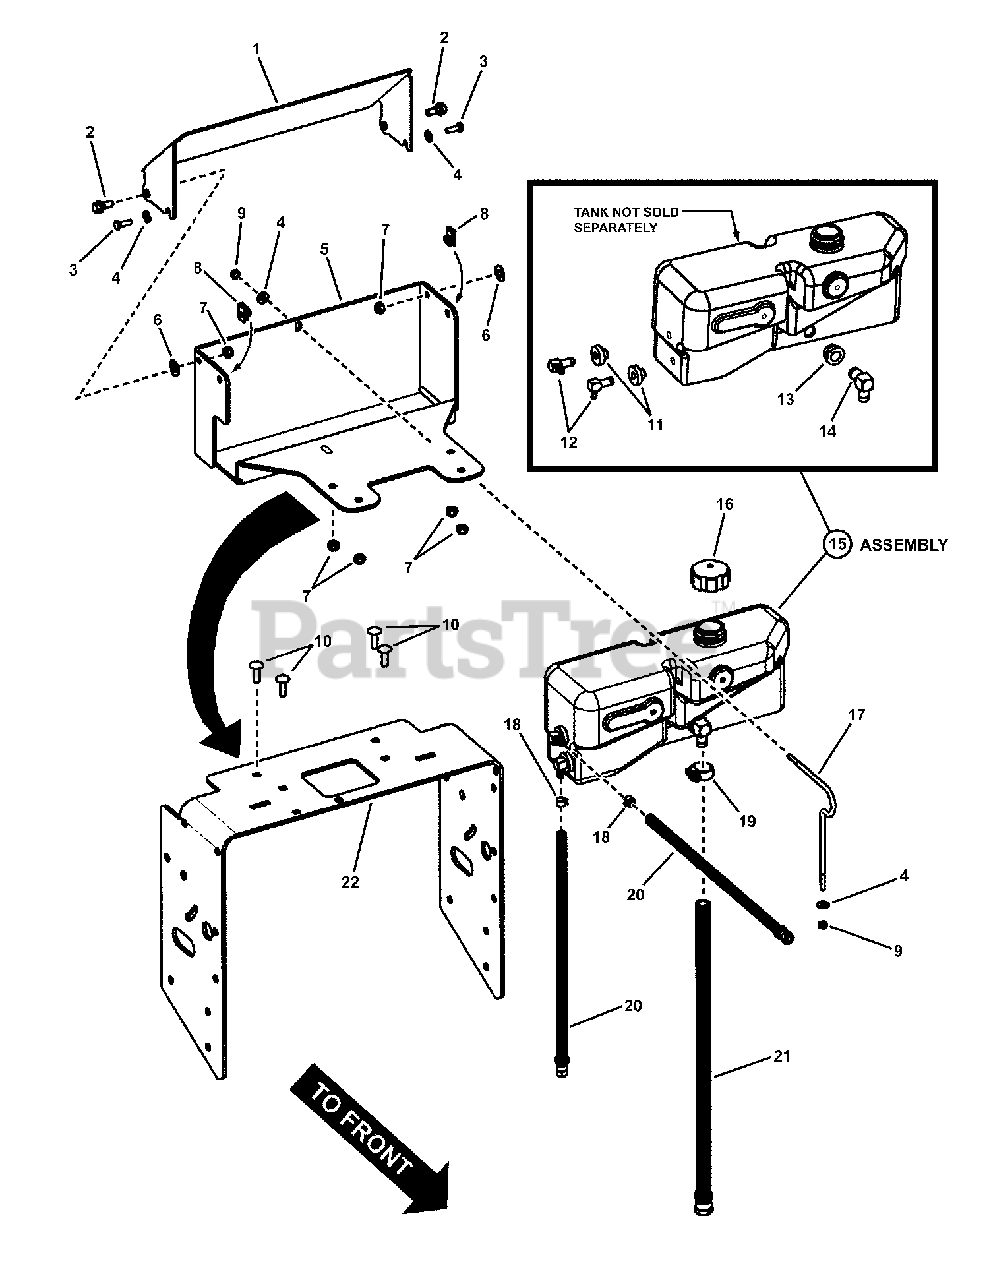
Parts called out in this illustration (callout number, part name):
1	COVER, Oil Tank Bracket
2	SHOULDER BOLT, 5/16-18
3	SCREW, 1/4-20 x 3/4" Hex Head Cap, GR 5
4	WASHER, .28 x .63 x .06 Flat
5	BRACKET, Reservoir, Hydro
6	WASHER, 3/8" Curved
7	NUT, 5/16-18 HEX NYLON LOCK
8	U-NUT 1/4-20
9	NUT, 1/4-20 Hex Top Lock, GR B
10	BOLT, 5/16-18 x 1" Short Neck Carriage, GR 5
11	GROMMET
12	*ELBOW
13	GROMMET
14	*ELBOW
15	OIL TANK (Includes Cap)
16	CAP, Oil Tank, Vented
17	RETAINING ROD, Reservoir (1/4-20 threads)
18	CLAMP, Fuel Hose
19	CLAMP, 13/16" Hose
20	HOSE, Return, 15-1/4" (7/16-20 Fitting on One End)
21	HOSE, 1/2 x 19-1/2" Supply (3/4-16 Fitting on One End)
22	WELDMENT, Tank Bracket- Hydro
